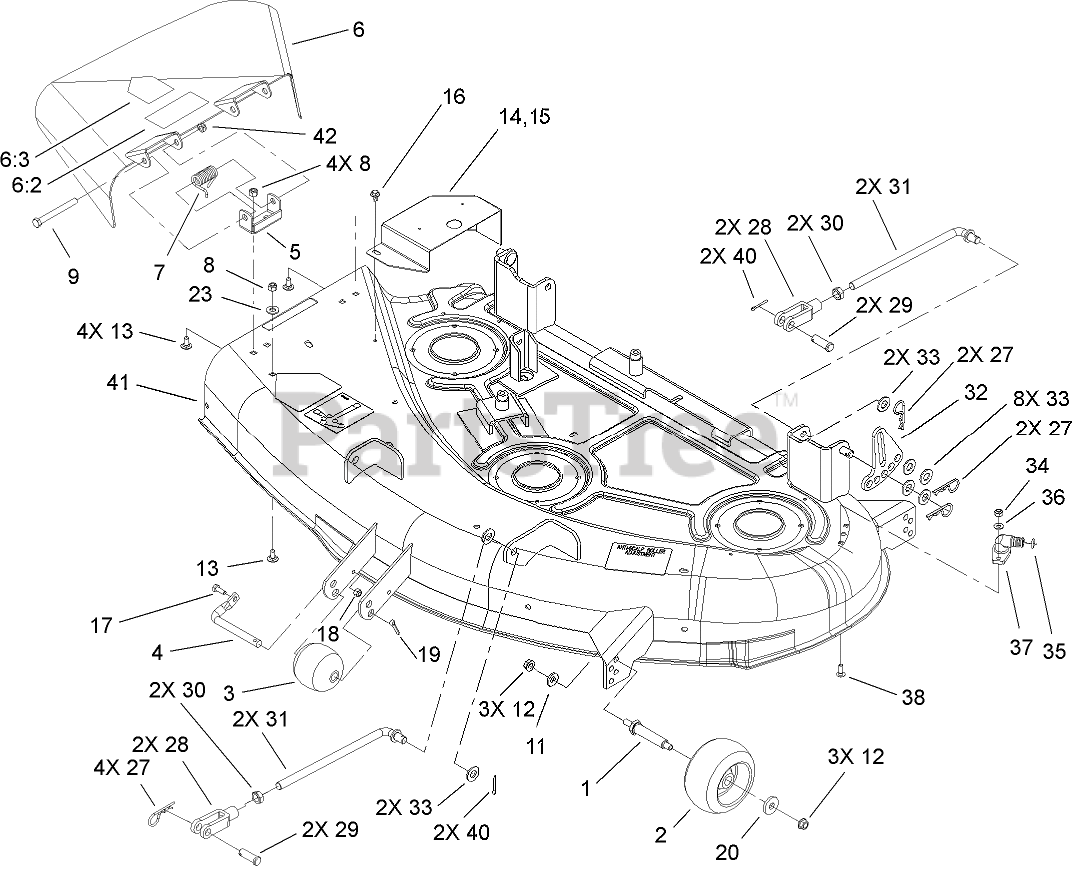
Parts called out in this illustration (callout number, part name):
1	SPACER
2	ROLLER-SCALP, ANTI
3	ROLLER
4	Shaft-Roller
5	BRACKET-PIVOT
6	DEFLECTOR ASM
6:2	DECAL-DANGER
6:3	DECAL-DANGER
7	SPRING
8	NUT-LOCK, NI
9	SCREW-HH
11	WASHER-BELLEVILLE
12	NUT-HHF, WHIZ
13	SCREW-CARR
15	COVER-BELT, RH
16	SCREW-HHFTF
17	SCREW-HH
18	NUT-LOCK, NI
19	PIN-COTTER
20	WASHER
23	WASHER-FLAT
27	PIN-COTTER
28	CLEVIS
29	PIN-CLEVIS
30	NUT-JAM
31	ROD-TRUNION
32	LINK-HOC, ADJUSTING
33	WASHER-FLAT
34	NUT-LOCK, NI
35	O-RING
36	WASHER-FLAT
37	FITTING-WASHOUT
38	BOLT-CARR
40	PIN-COTTER
41	44 INCH DECK ASM
42	NUT-HEX
